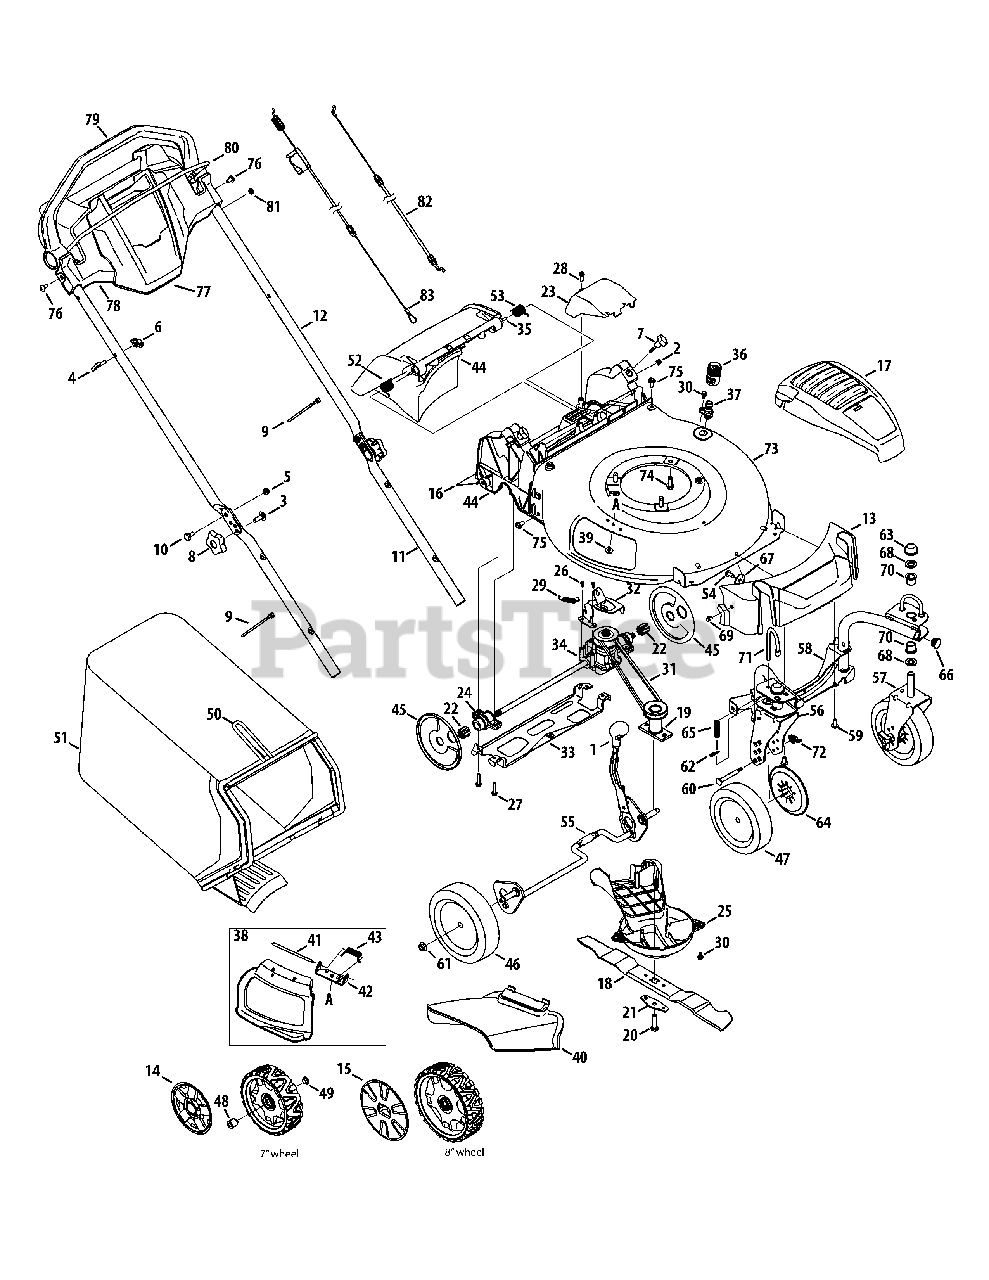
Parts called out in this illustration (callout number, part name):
1	Adjustment Knob
2	Nut, Sq., 1/4-20
3	Carriage Screw, 5/16-18
4	Rope Guide
5	Nut, Flange Lock, 1/4-20
7	Wing Nut
9	Cable Tie
10	Shdr. Screw, .375 x .126 x 1/4-20
11	Lower Handle
12	Upper Handle
13	Front Cover
14	Hubcap, 7"
15	Hubcap, 8"
16	Trail Shield
17	Engine Shroud
17	Screw, #10-16 X 1.25
18	Mulching Blade
19	Blade Adapter
20	Screw, 3/8-24 x 1.50
21	Blade Bell Support
22	Spur Gear, 10T
23	Transmission Cover
24	Bearing Assembly
25	Engine Baffle
26	Screw, Hex Washer, .159 x .43
27	Screw, 1/4-15 x 1.25
28	Screw, 1/4-15 x .750
29	Exten. Spring, 2.405
30	Screw, Shldr., 1/4-20 x .50
32	Transmission Bracket
33	Rear Support Bracket
34	Transmission Assembly
36	Water Nozzle Adapter
37	Water Nozzle
38	Mulch Plug (Incl. 41-43)
40	Side Discharge Chute
42	Chute Deflector Bracket
43	Torsion Spring
44	Rear Discharge Door Assembly
45	Wheel Dust Cover
46	Rear Wheel, 8 x 2
47	Front Wheel, 7 x 2
48	Caster Hub, Long
49	Caster Hub, Short
50	Grass Catcher Frame
52	Torsion Spring - RH
53	Torsion Spring - LH
54	Self Tapping Screw, 5/16-18 x .750
55	Rear Axle Assembly
56	Caster Bracket Assembly, RH
57	Caster Bracket Assembly, LH
58	Caster Bracket Assembly
59	Screw, 5/16-14 x .750
60	Caster Axle, .374 Dia. x 2.59
61	Flange Lock Nut, 3/8-16
62	Cotter Pin, .072 Dia. x 1.13 Lg.
63	Push Cap, 5/8
64	Dust Cover, 7"
65	Compr. Sprng., .531 OD x 1.75 Lg
67	Washer, Flat, .330 x 1.25 x .06
68	Flat Washer, .640 x 1.12 x .125
69	Shdr. Screw, .50 x 1/4-20
70	Flange Bearing, .631 ID
71	Lock Pin: Front Wheel
72	Wing Nut, 1/4-20 w/Bell Washer
73	21" Deck
74	Screw, tt, 3/8-16 x 1.00
75	Screw, 5/16-14 x .750
76	Screw, 1/4-14 x .625
77	Trim Console
78	handle Console
79	Drive Handle
80	Blade Control
81	Shoulder Spacer, .18 x .315 x .09
82	Control Cable
83	Drive Cable
